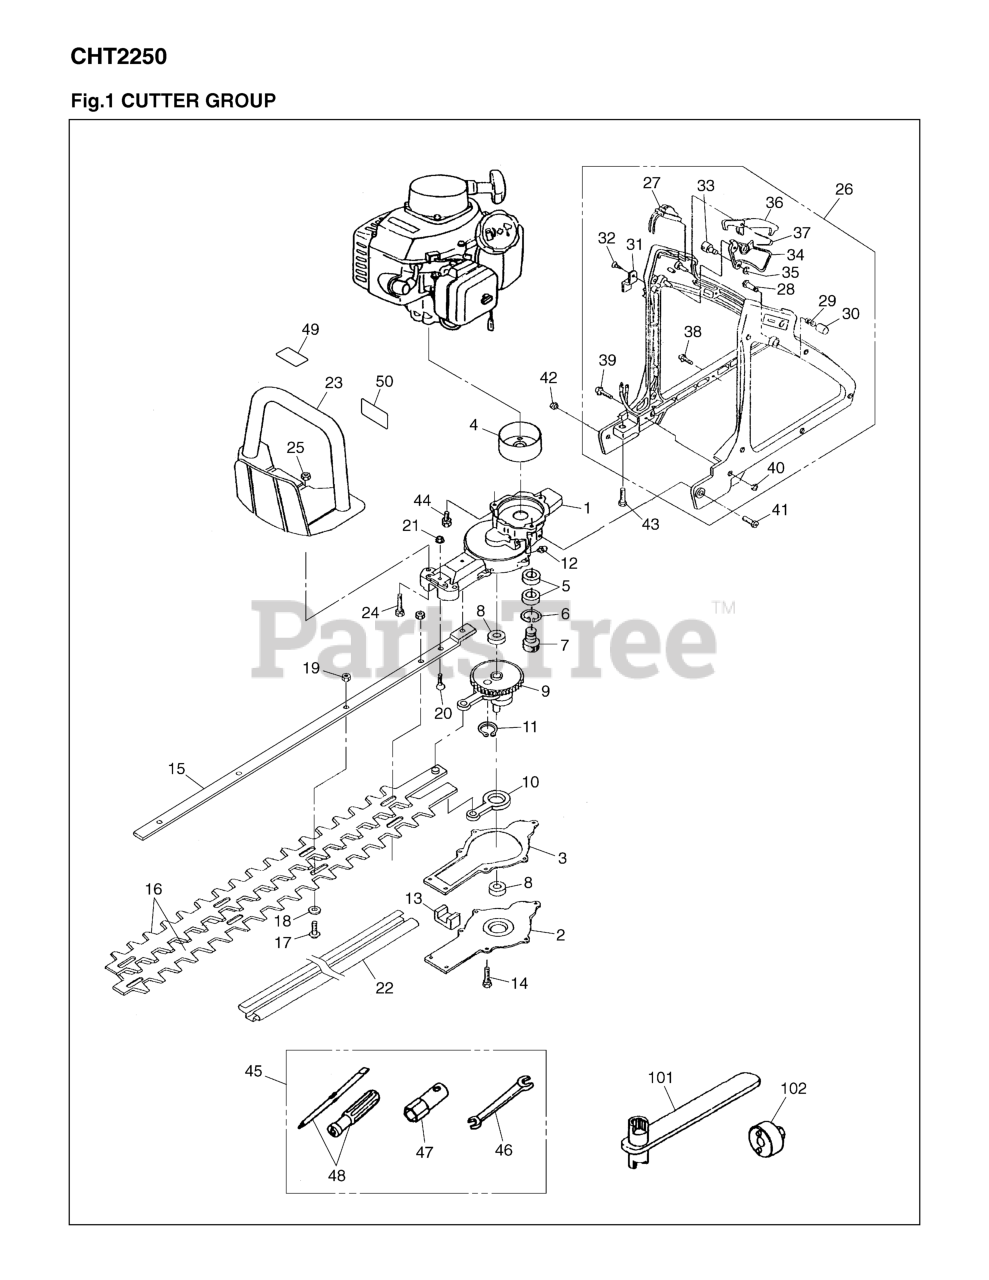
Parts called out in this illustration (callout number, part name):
1	GEARCASE
2	COVER
3	GASKET
4	DRUM, CLUTCH
5	BEARING
6	RING, SNAP
7	PINION
9	GEAR COMPL
10	ROD
11	RING, SNAP, M25 X 1.2
12	FITTING, GREASE
13	FELT
14	BOLT
15	PLATE, GUIDE
16	BLADE
18	WASHER
19	NUT
20	SCREW
21	NUT
22	COVER, BLADE
23	HANDLE, FRONT
24	BOLT
25	NUT M6
26	HANDLE, REAR ASSY (RPL 3873-)
27	SWITCH
29	SPRING
30	CAP, PIN
31	PLATE
32	SCREW, M4 x 10
33	END, CABLE
34	LEVER, THROTTLE (RPLS -13220)
35	RING, SNAP
37	SPRING (REPLACES -13321)
38	SCREW, M4 X 16
39	SCREW, M4 x 30
40	NUT, M6 X 4
41	BOLT, M6 X 50
42	NUT M6
43	BOLT, M6 X 40
44	BOLT, M6 X 14
45	TOOL SET
46	SPANNER
47	SOCKET, HEX, 3/4
48	DRIVER
49	LABEL
102	WRENCH (TOOL)
